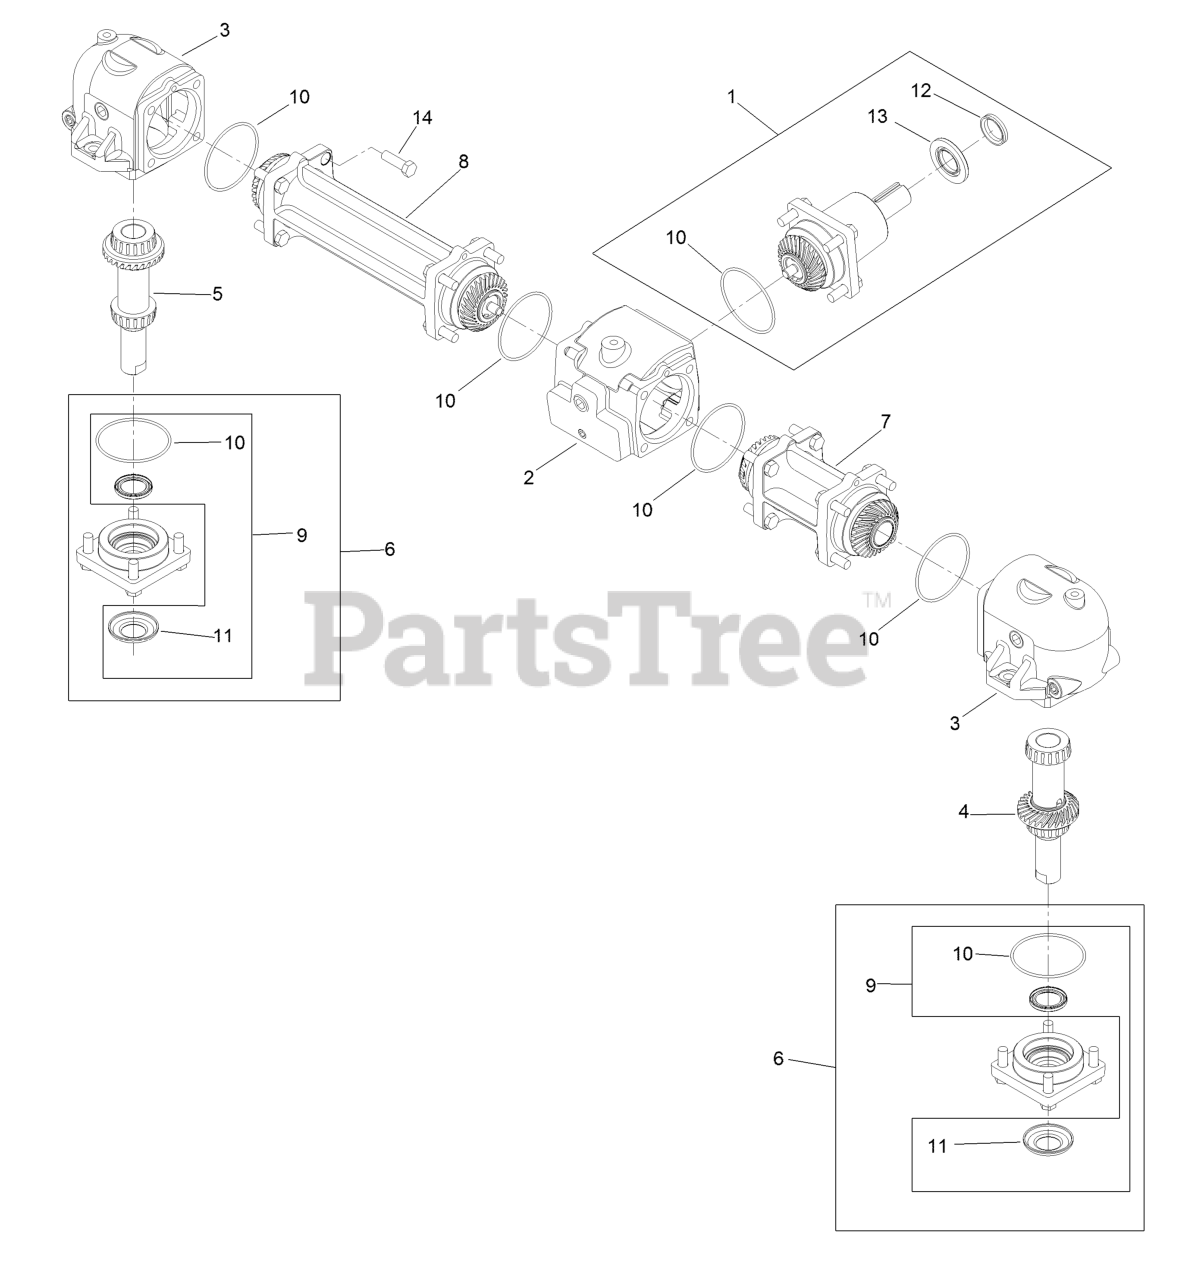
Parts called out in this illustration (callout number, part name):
1	Input Pinion ASM
2	Housing-Center
3	Housing-End
4	LH Output Shaft And Gear ASM
5	RH Output Shaft And Gear ASM
6	Cap-Output
7	Tube-Connector, Short
8	Tube-Connector, Long
9	Output Seal Kit
10	Seal-O-Ring
11	Washer-Cupped
12	Seal-V-Ring
13	Seal-Input
14	Bolt-Blade
